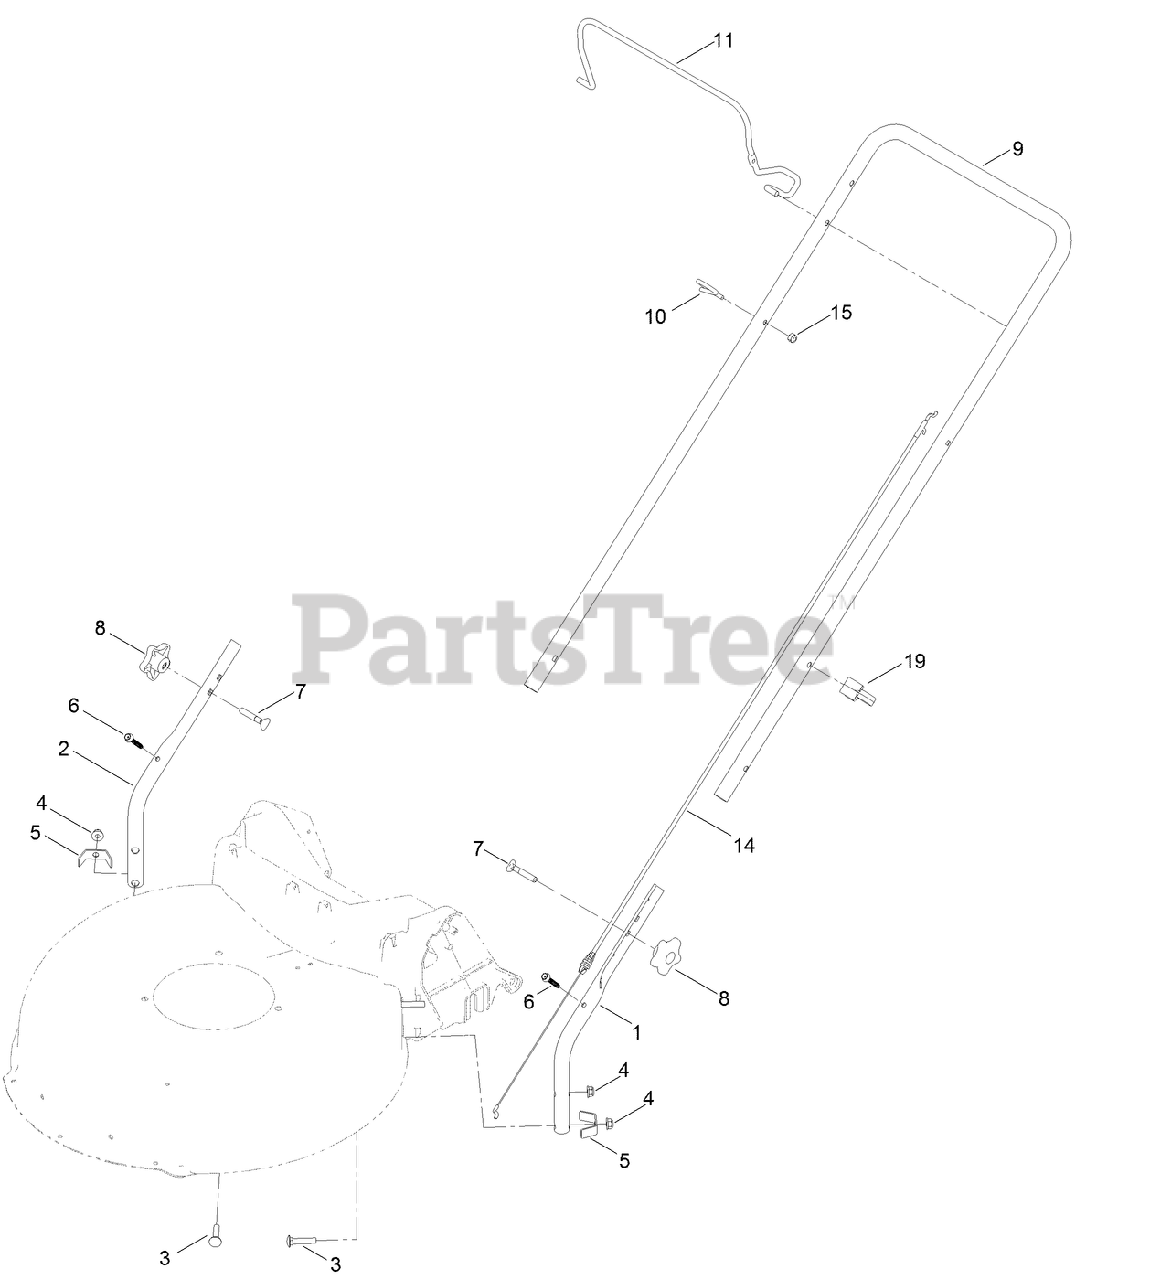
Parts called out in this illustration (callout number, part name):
1	HANDLE-LOWER, LH
2	HANDLE-LOWER, RH
3	BOLT-CARR
4	NUT-FLANGE, NI
5	BRACKET-CHUTE
6	SCREW-FLANGE, SERRATED
7	SCREW-HANDLE
8	KNOB-HANDLE
9	HANDLE-UPPER
10	GUIDE-ROPE
14	CABLE-BRAKE, ENGINE
15	NUT-LOCK, NI
19	GUIDE-CABLE
